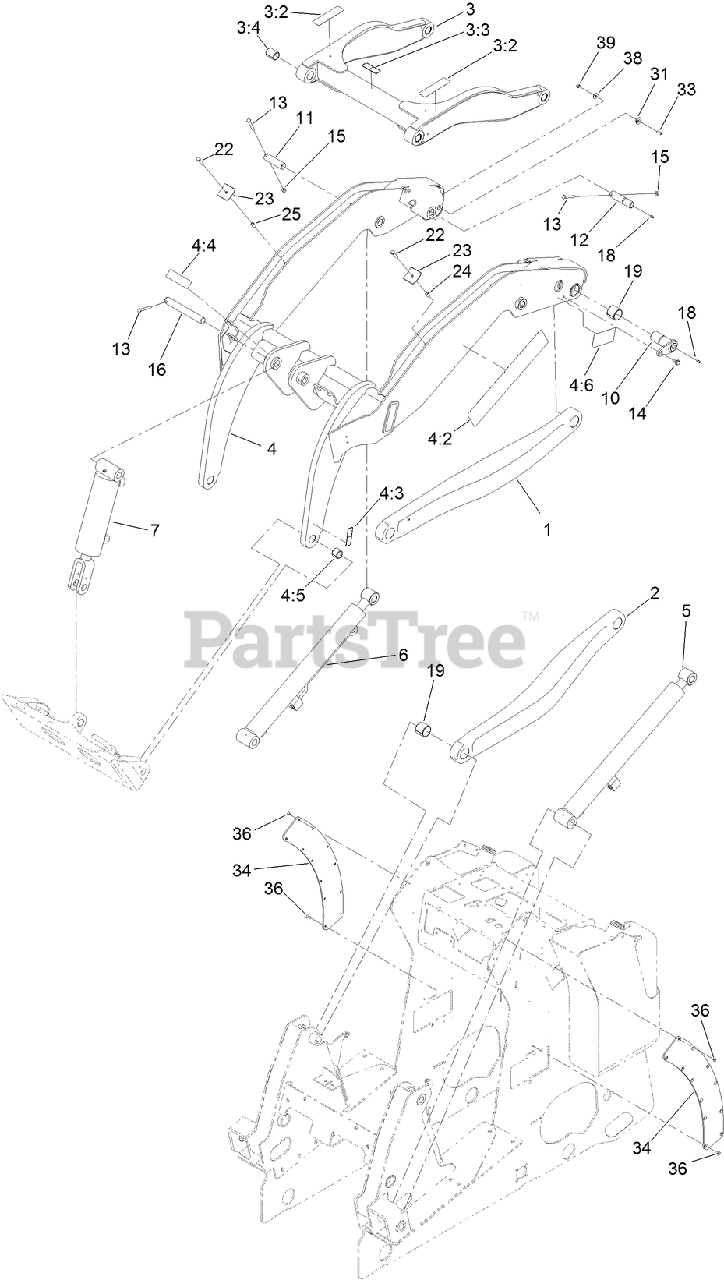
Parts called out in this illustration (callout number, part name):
1	LINK-LOWER, LH
2	LINK-LOWER, RH
3	LINK-UPPER
3:2	DECAL-WARNING, CRUSHING
3:3	DECAL-WARNING, PINCH POINT
3:4	BUSHING-SPRING
4	ARM-LOADER
4:2	DECAL-TX1000,
4:3	DECAL-WARNING, PINCH POINT
4:4	DECAL-CAUTION
4:5	BUSHING-TENSION
4:6	DECAL-WARNING, PINCH POINT
5	CYL-HYD LH
6	CYL-HYD RH
7	CYL-HYD
10	PIN-PIVOT
11	PIN-PIVOT
12	PIN-LINK
13	SCREW-HSH
14	BOLT-SHOULDER
15	NUT-LOCK, NI
16	PIN-LOCKING
18	FITTING-GREASE
19	BUSHING-SPRING
22	SCREW-HH
23	PLATE-HOLDDOWN, HOSE
24	SPACER-HOSE
25	SPACER-HOSE
33	SCREW-HSBH
34	PAD-WEAR, FRAME
36	SCREW
38	WASHER-PLAIN
39	NUT-LOCK, NI
